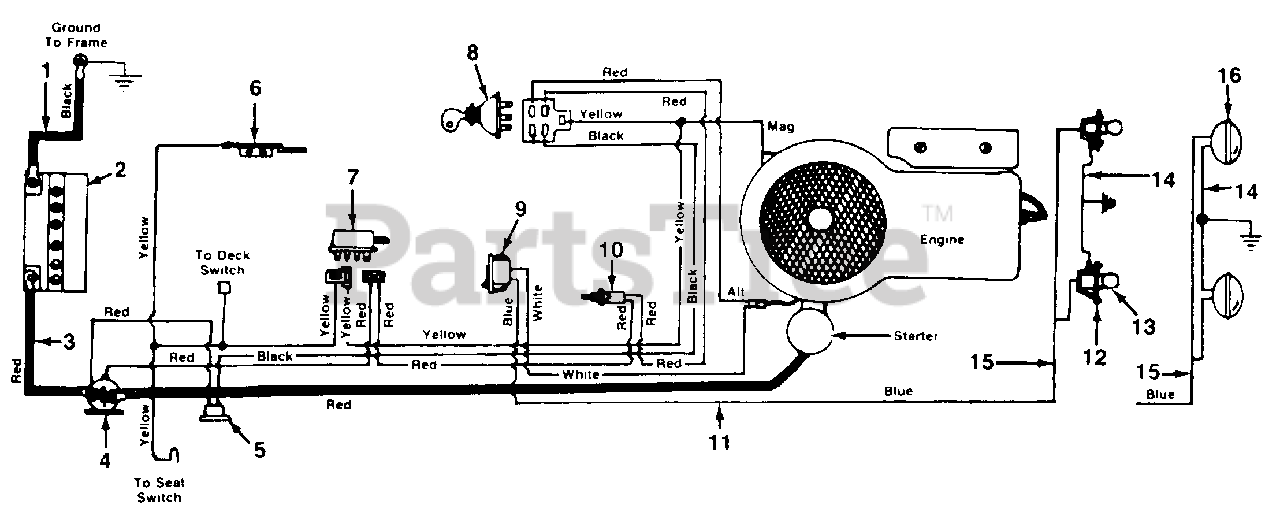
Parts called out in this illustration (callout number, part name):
1	Ground Wire
2	Battery
3	Electric Wire
4	Solenoid
5	Circuit Breaker
6	Spring Switch
7	Safety Switch
8	Key Switch
9	Light Switch
10	Safety Switch (Black)
11	Harness
12	Socket
13	Lamp
14	Ground Wire
15	Headlight Harness
16	Lamp
